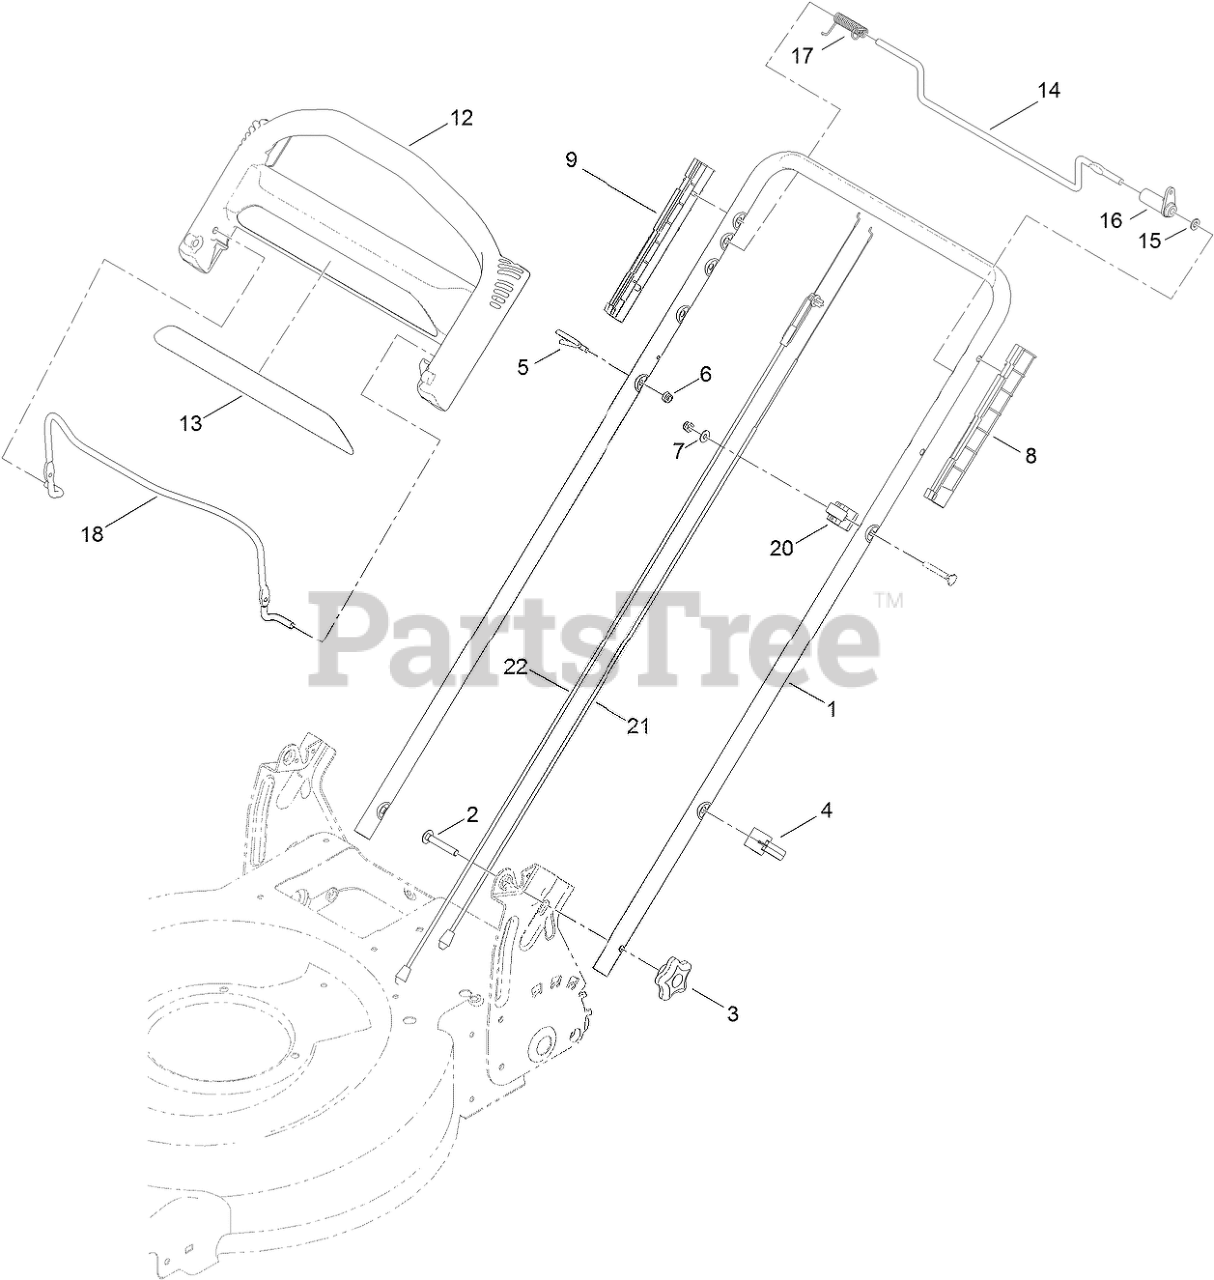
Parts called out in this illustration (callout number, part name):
2	Screw-CARR
3	KNOB-HANDLE
4	GUIDE-CABLE
5	GUIDE-ROPE
6	NUT-LOCK, NI
7	WASHER-FLAT
8	GUIDE-LH
9	GUIDE-RH
12	HANDLE-CONTROL
14	BAR-CONTROL, TRACTION
15	WASHER-PLAIN
16	LEVER-TRACTION
17	Spring-Torsion
18	Bail-Brake
20	ANCHOR-CABLE
21	CABLE-TRACTION
22	CABLE-BRAKE
